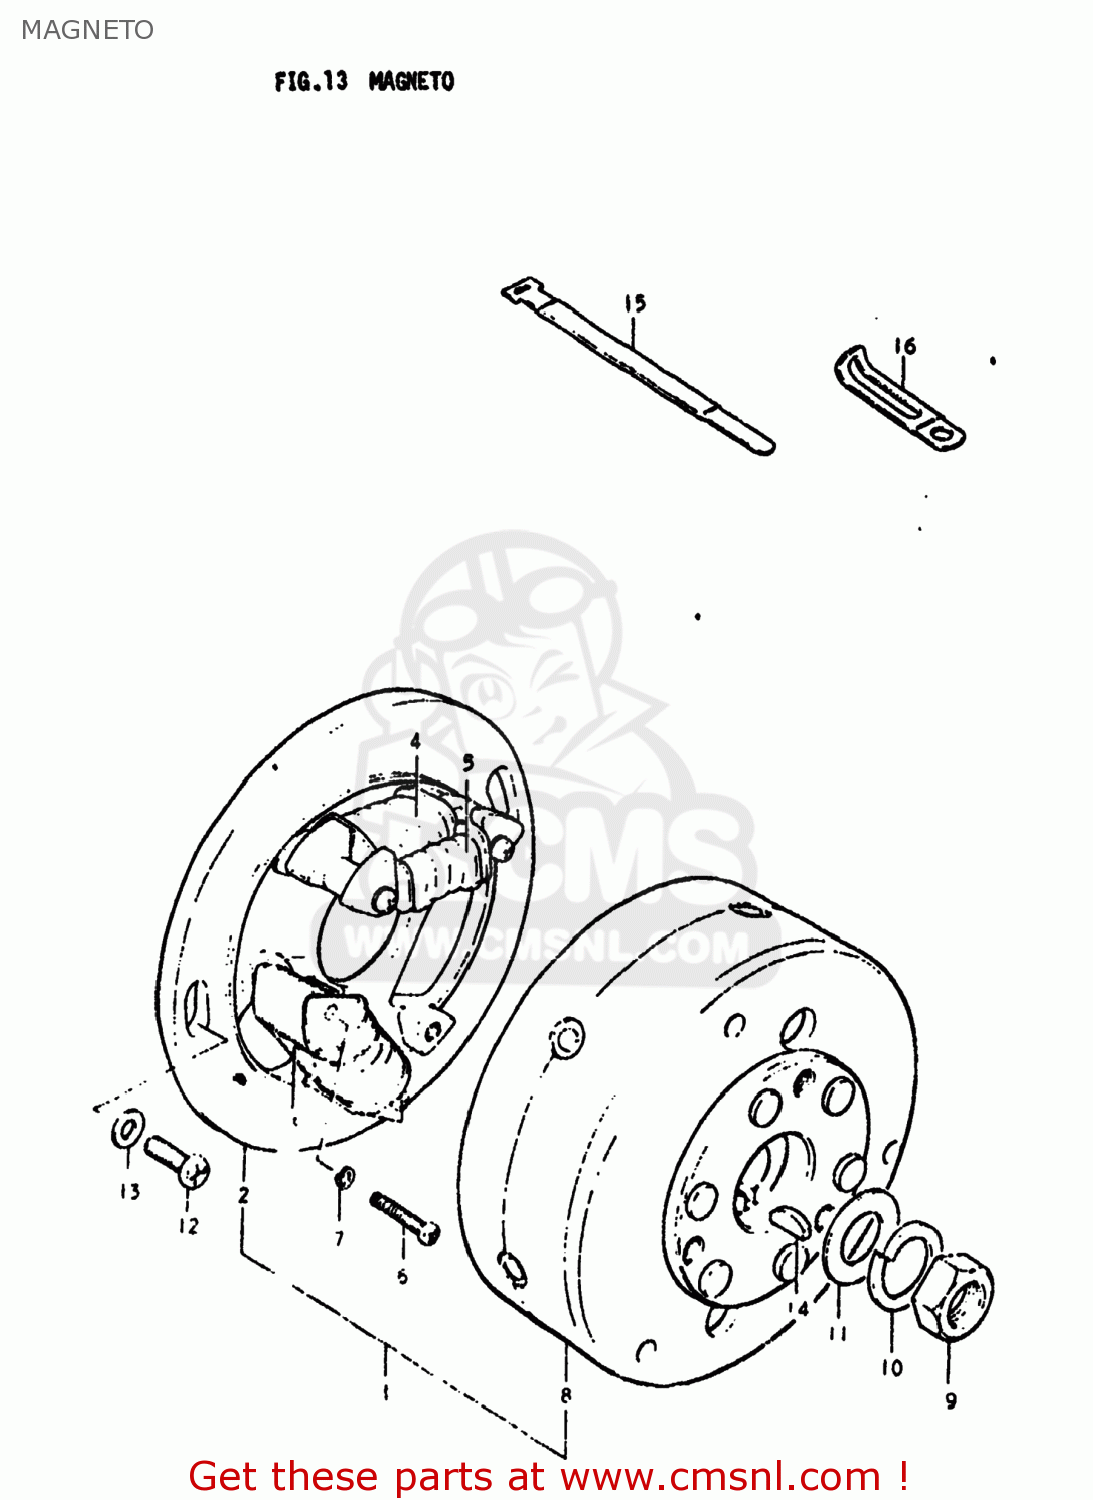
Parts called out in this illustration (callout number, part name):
1	MAGNETO ASSEMBLY
2	STATOR ASSEMBLY
3	COIL,LIGHTING
4	COIL
5	COIL,PULSER
6	SCREW
7	LOCK WASHER
8	ROTOR ASSEMBLY
9	NUT (10MM)
10	LOCK WASHER
11	WASHER
12	SCREW
13	WASHER
14	KEY 4MM
15	CLAMP
16	CLAMP
